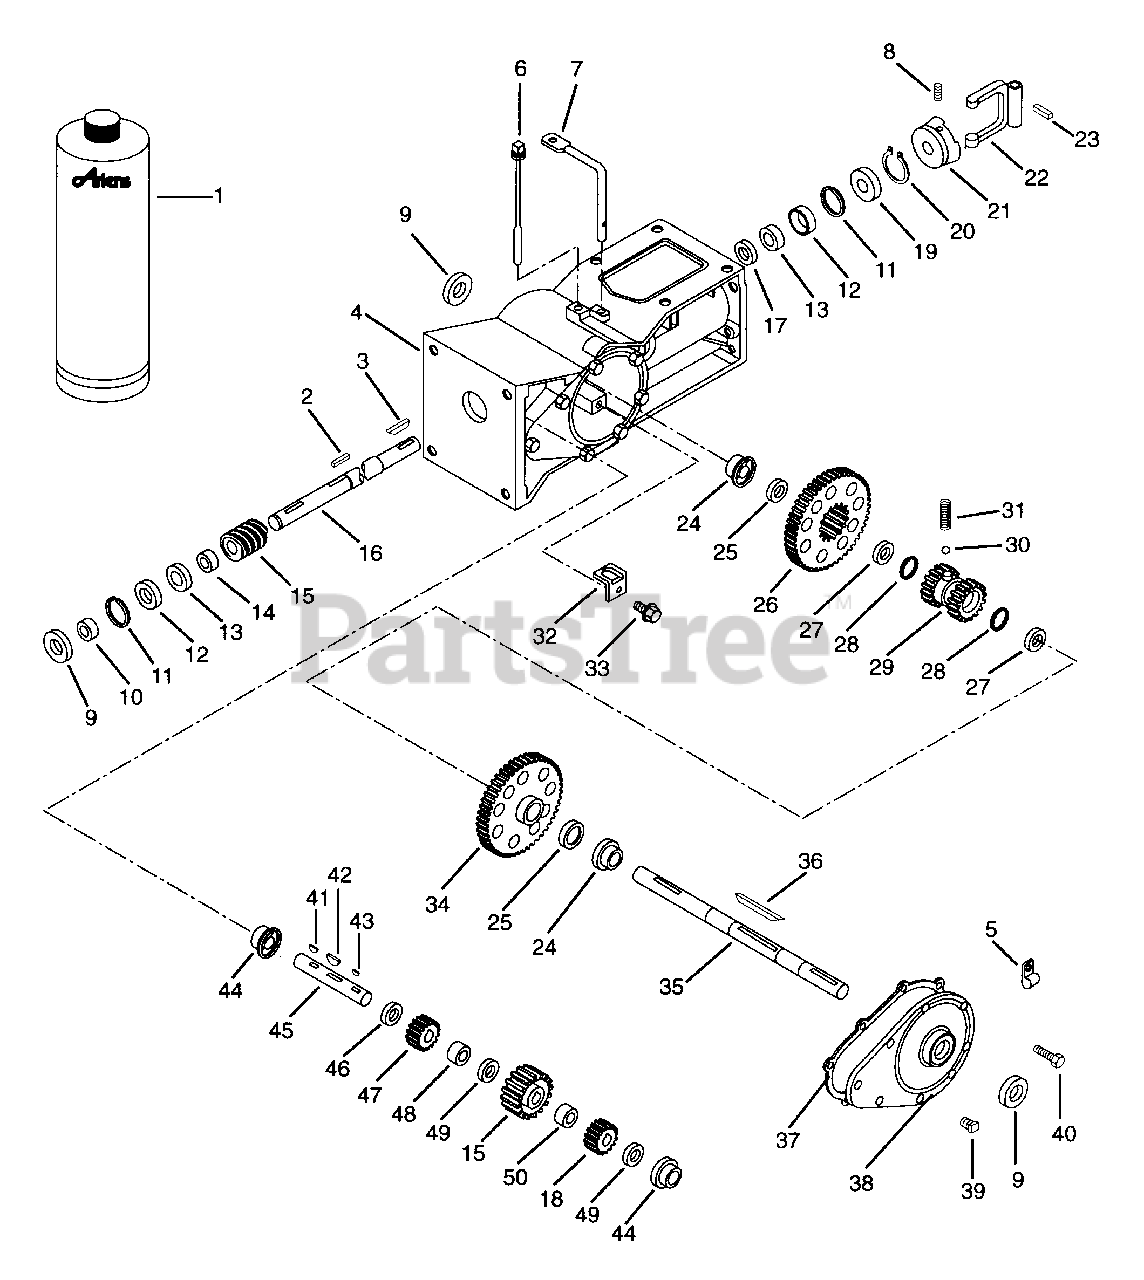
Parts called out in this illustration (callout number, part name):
1	ARIENS 16 OZ.BOTTLE OF L2 LUBE
2	KEY-SQ .188X1.0X.188 SAE 8630
3	KEY-FTHR .188X1.25X.187 SAE
4	TRANSMISSION HOUSING
5	CLAMP, CUSHIONED STEEL
6	DIP STICK
7	HIGH-LOW SHIFT LEVER
8	SCR-SET .32-18X.38 SKHCUPNL OH
9	SEAL 1.000X1.785X.250
10	SPACER BUSHING .99 X .75 X .50
11	RG-RTNG-INT 1.781X.052
12	BRG-CUP 1.781X.475
13	BRG-CONE .750X.61
14	BSHG, SPCR .755X1.12X.50 PM
15	WORM AND WORM GEAR
16	WORM SHAFT
17	WSHR-FL-STL .755X1.375X.125
18	LOW PINION
19	SEAL .750X1.781X.250
20	RG-RTNG-EXT .750X.078
21	TILLER DRIVING JAW
22	SHIFT YOKE
23	PIN-ROLL .250X1.00
24	BSHG-FLG 1.000X1.25X1.000X1.50
25	WSHR-HRD-THRS 1.007X1.542X.062
26	HIGH GEAR ASSY
28	RG-RTNG-EXT 1.00X.078
29	CLUTCH HUB
30	STEEL BALL
31	SG-COMP .047X.31X.593 WLD11
32	RETAINER CLIP
33	SCR-TAP 10-24X.75 HWH PL TR
34	LOW GEAR
35	AXLE SHAFT
36	KEY-FTHR .25X2.75X.25 SAE1035
38	TRANSMISSION COVER
39	PIPE PLUG
40	SCR-TAP .312-18X1.0 HWH PL TR
41	KEY-WDRF .188X.625X.31 SAE9MOD
42	KEY-WDRF .25X.687X.375
43	KEY-WDRF .188X.75X.313 SAE 9
44	BSHG-FLG .750X1.000X.750X1.250
45	SHAFT, PINION
46	WSHR-HDND-THRST .760X1.25X.094
47	HIGH PINION
48	SPACER 1.25 X .75 X .75
49	WSHR-HDND-THRST .758X1.23X.031
50	SPACER 1.25 X .75 X .75
